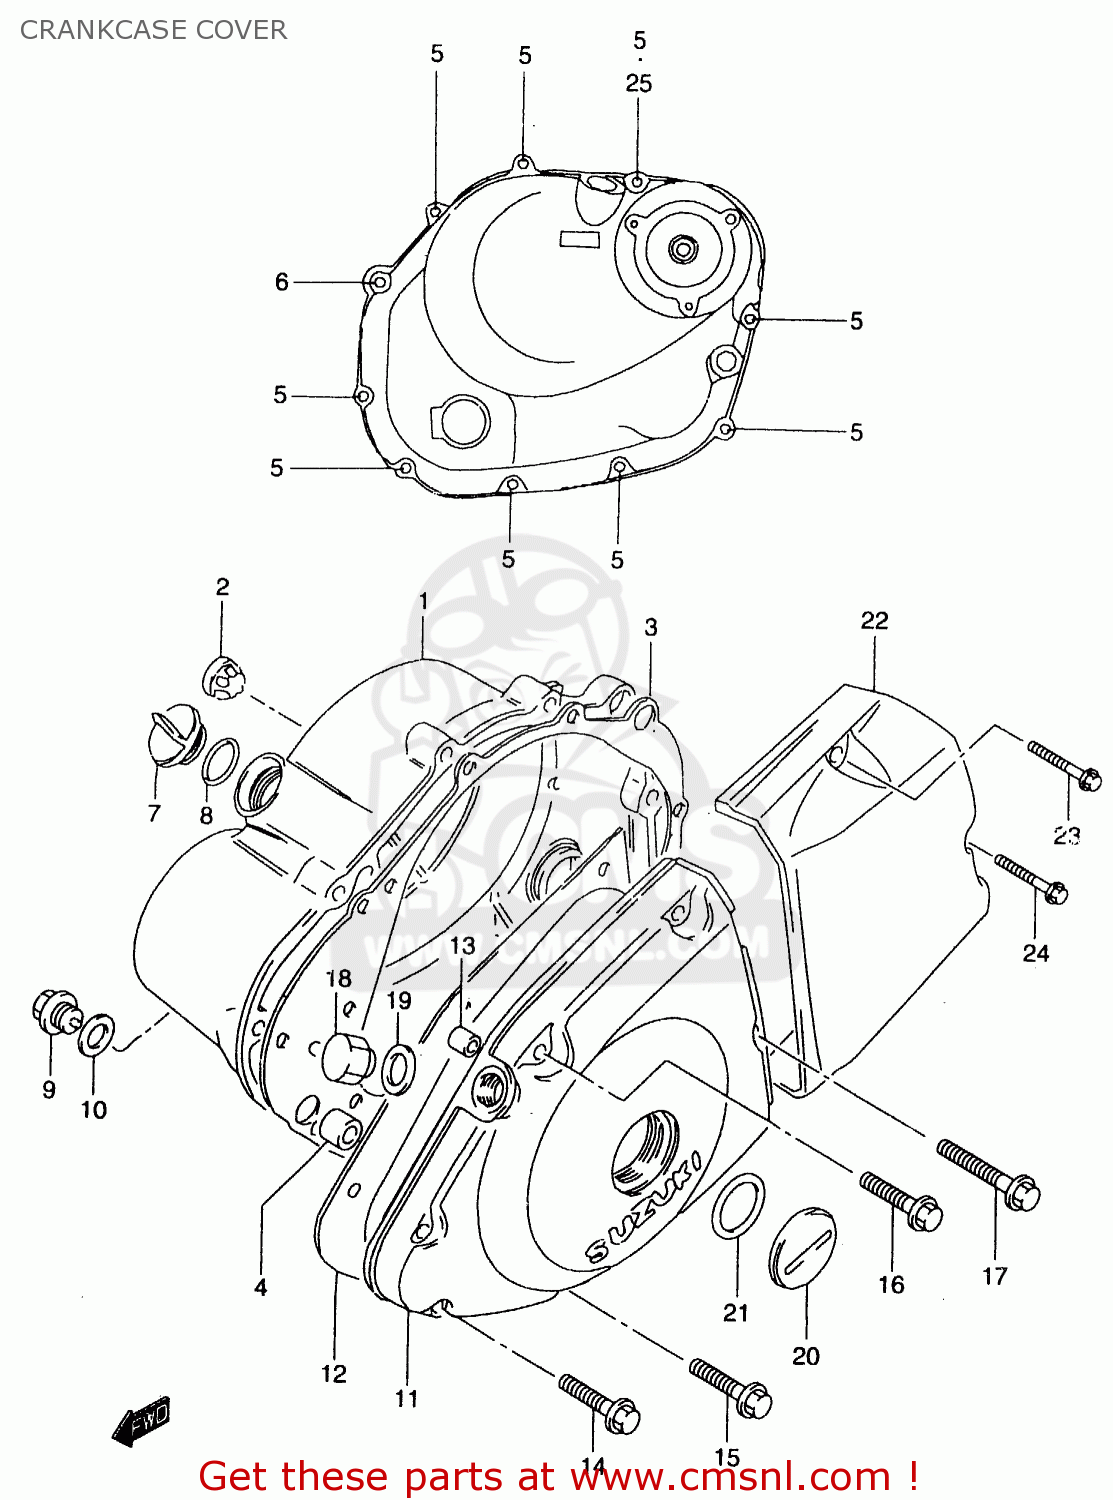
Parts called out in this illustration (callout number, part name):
1	COVER,CLUTCH
2	LENS,OIL LEVEL CHECK
3	GASKET,CLUTCH COVER (NAS)
4	PIN
5	BOLT
6	BOLT
7	PLUG(20X10)
8	O RING(D:3.1,ID:16.8)
9	PLUG(14X12)
10	GASKET(13.8X18.8X4.8) (NAS)
11	COVER,MAGNETO
12	GASKET,MAGNETO COVER (NAS)
13	PIN
14	BOLT
15	BOLT
16	BOLT
17	BOLT
18	PLUG,12X9
19	GASKET(12.1X16.2X3.7) (NAS)
20	PLUG(26X9)
21	O RING(D:3.1,ID:22.7)
22	COVER,ENGINE SPROCKET
23	BOLT
24	BOLT
25	GASKET(5.8X11X1.2) (NAS)
